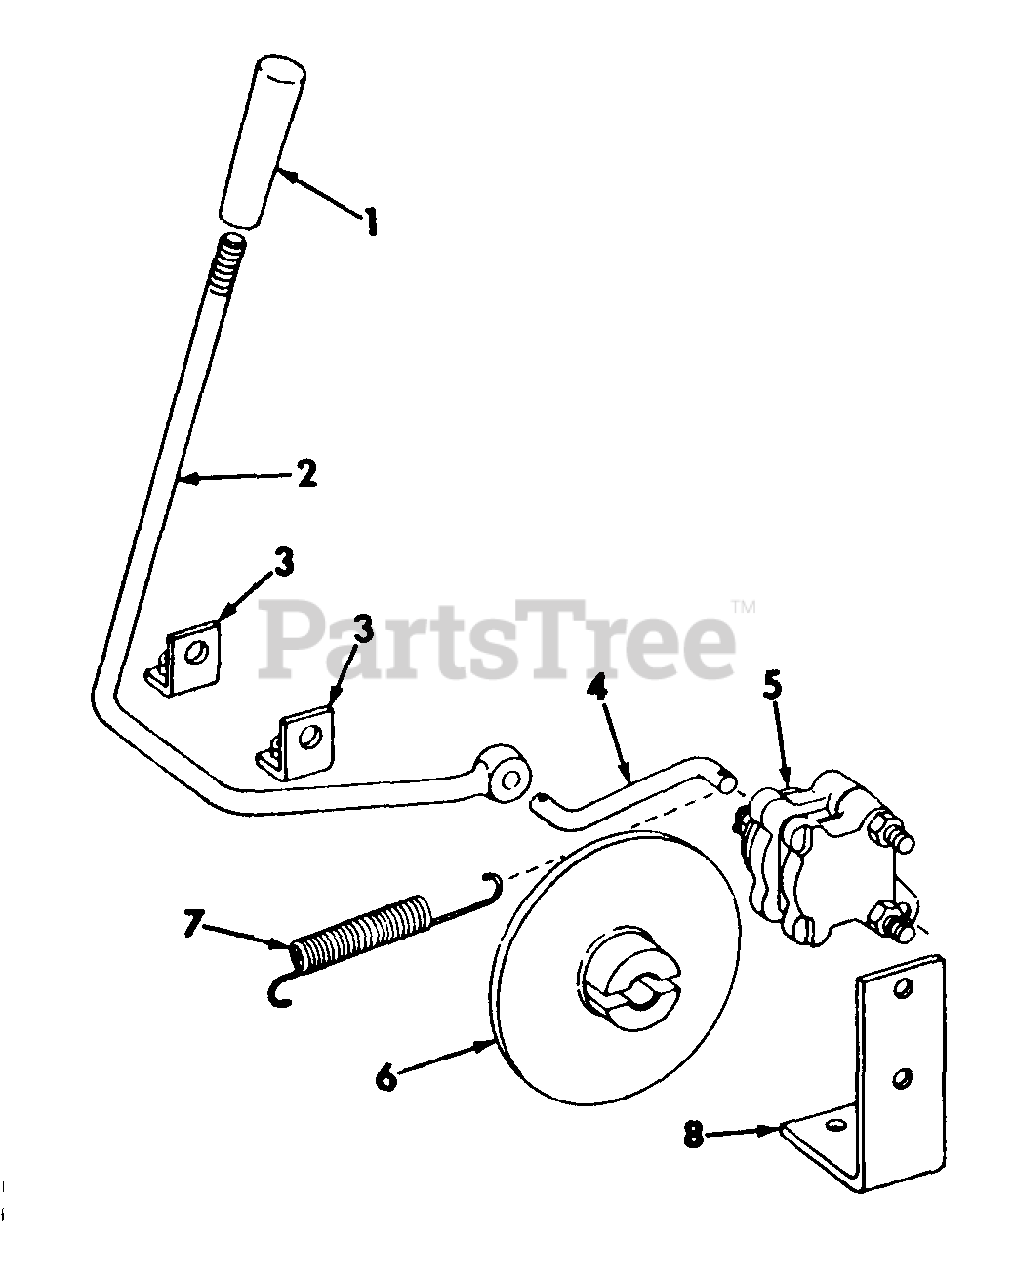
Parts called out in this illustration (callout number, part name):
1	GRIP, SHIFTER HANDLE
2	LEVER, PARK BRAKE
3	BRACKET ASSY, BRAKE LEVER
5	BRAKE, DISC
6	HUB ASSY, BRAKE DISC
7	SPRING, BRAKE RETURN
8	BRACKET, BRAKE
